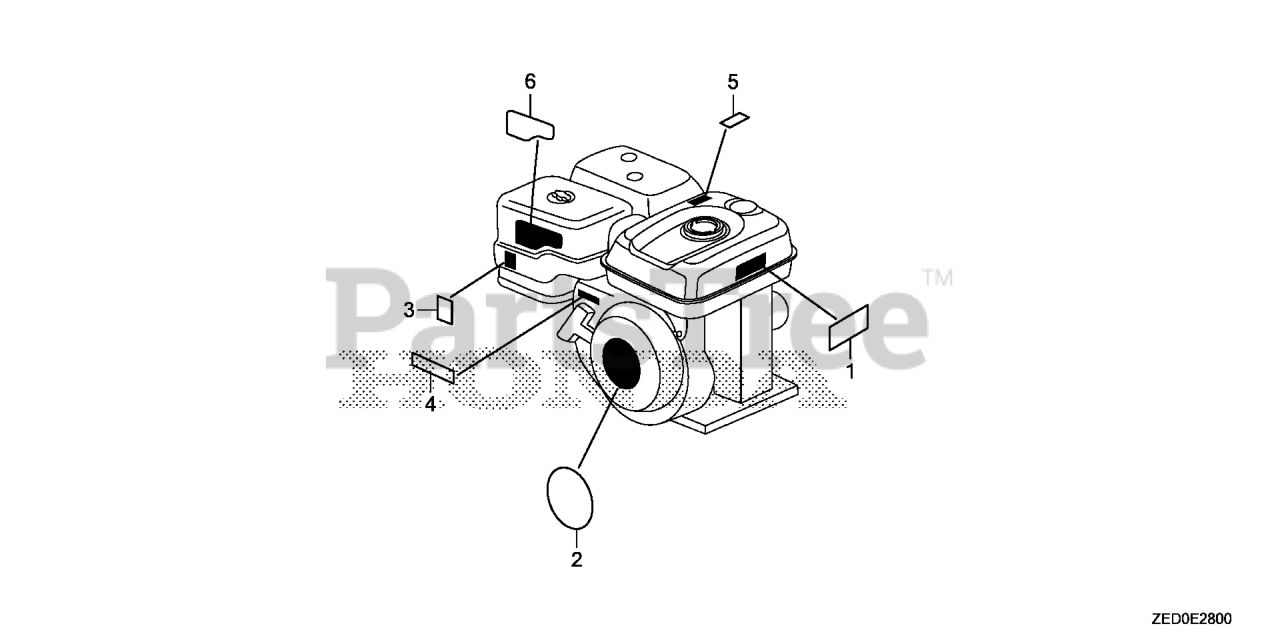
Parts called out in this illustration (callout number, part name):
1	MARK, OPERATOR CAUTION (PICTOGRAPH)
2	EMBLEM (GX160)
3	MARK, CHOKE
4	MARK, THROTTLE INDICATION
